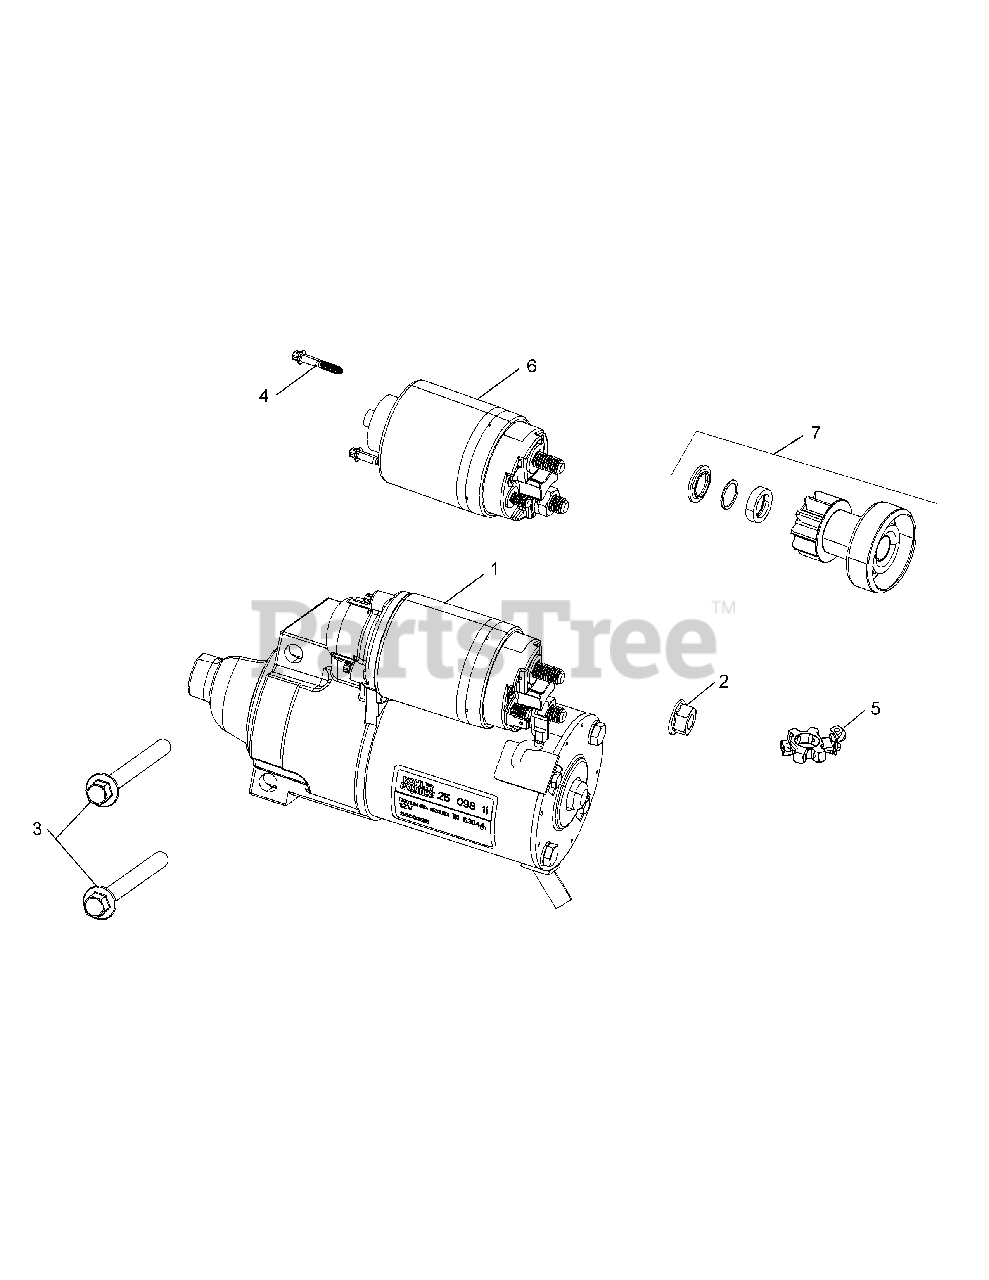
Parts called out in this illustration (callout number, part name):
1	Solenoid Shift Starter Assembly
2	Flange Nut, M8x1.25
3	Flange Screw, M8 x 1.25 x 80
4	Torx Head Screw
5	Brush Holder Kit
6	Solenoid Kit (Inc. 4)
7	Starter Pinion Kit
